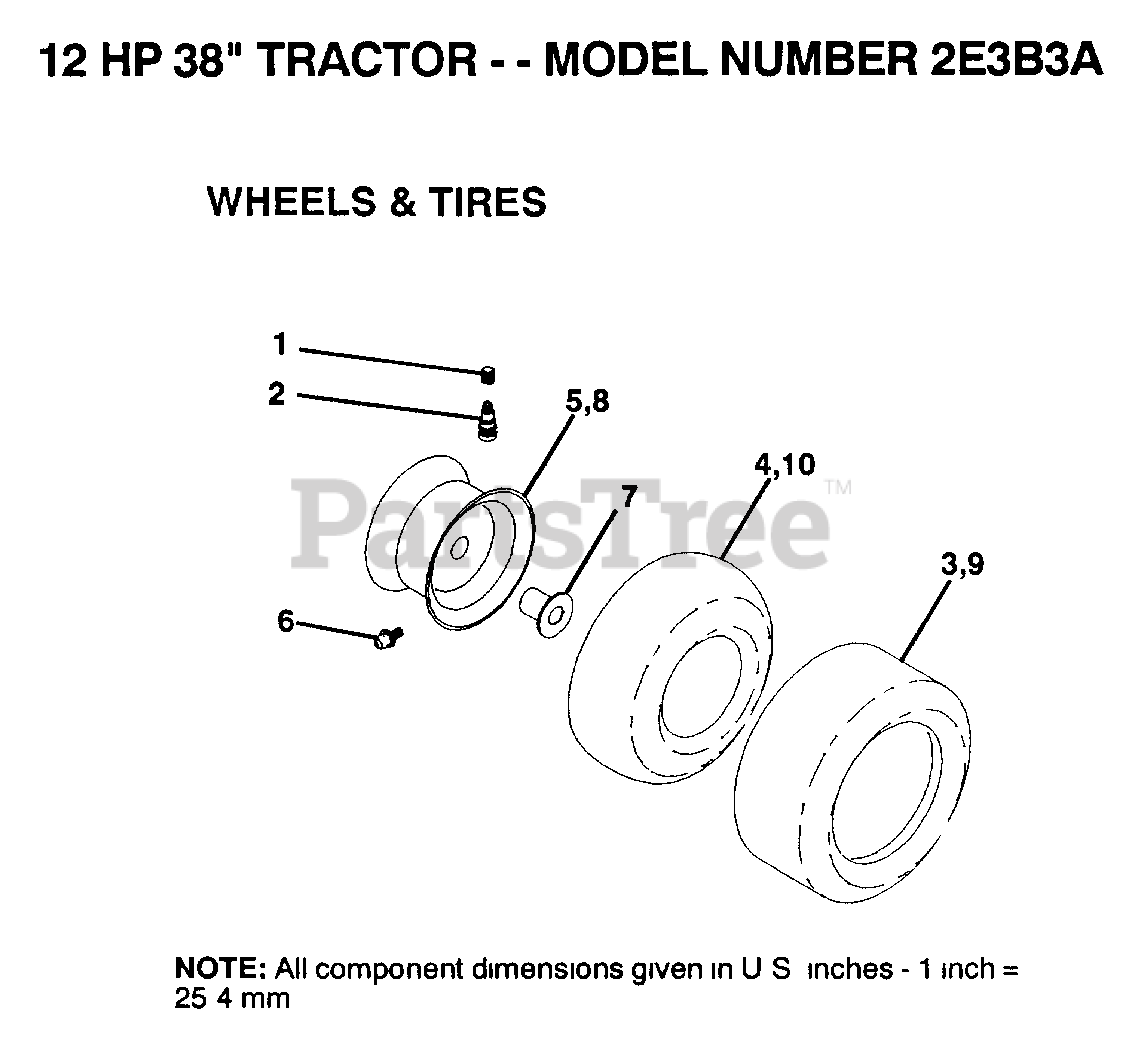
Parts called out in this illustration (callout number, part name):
1	VALVE CAP
2	VALVE STEM LT
4	TUBE.5.3/4.5/6
6	FITTING LT
7	"FLANGE, BEARING"
10	TUBE.18X9.5-8
